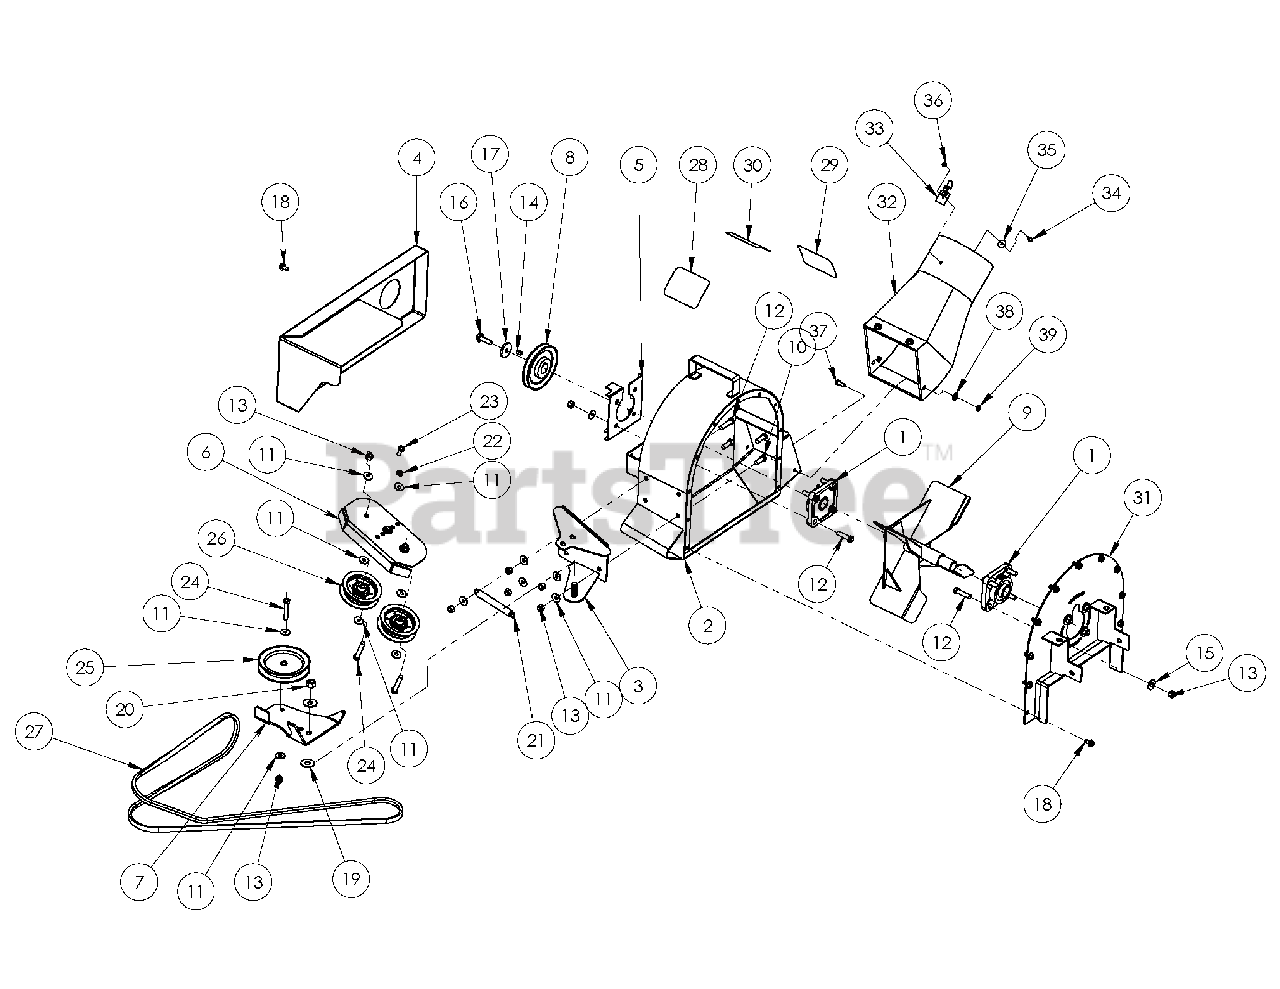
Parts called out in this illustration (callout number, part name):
2	15" VERTICAL BLOWER HOUSING
3	IDLER MOUNT W/A 15" BLOWER
4	EXTERIOR PULLEY COVER 15" BLOWER
5	5" BLOWER PULLEY BELT GUIDE
6	UPPER IDLER MOUNT PLATE
7	IDLER
8	DRIVE PULLEY
9	IMPELLER ASSEMBLY
10	CAP SCREW 3/8-16 X1 LONG
11	5/16" FLAT WASHER
12	CAP SCREW 3/8-16 X 1.50 LONG
13	3/8-16 NYLON INSERT NUT
14	KEY 1/4 SQ X .50 LONG
15	3/8 WASHER SAE
16	CAP SCREW SERATED FLANGE 3/8-16 X 1.25 LONG
17	FLAT WASHER,HEAVY
18	SELF-TAPPING SCREW 5/16 - .625
19	1/2" FLAT WASHER
20	1/2-13 NYLON INSERT NUT
21	BELT DRIVE TENSION SPRING
22	5/16 LOCKWASHER
23	CAP SCREW 5/16-18 X .75 LONG
24	CAP SCREW 3/8-16 X 2.00 LONG
25	INSIDE IDLER
26	IDLER PULLEY, 3" HIGH FLANGE, 3/8" ID
27	BELT, 44" DECK
27	BELT, 48/52" DECKS
28	THROWN OBJECT LABEL
29	TURN OFF MOWER LABEL
30	ROTATING BLADES LABEL
31	ENFORCER BLOWER MOUNT
32	Transition Chute
33	SPRING CLIP
34	#10 x 3/4 SCREW
35	#10 FENDER WASHER
36	#10-24 Nylon Insert Nut
37	CAP SCREW -1/4-20 x .75 LONG
38	1/4" WASHER
39	1/4-20 Nylon Insert Nut
